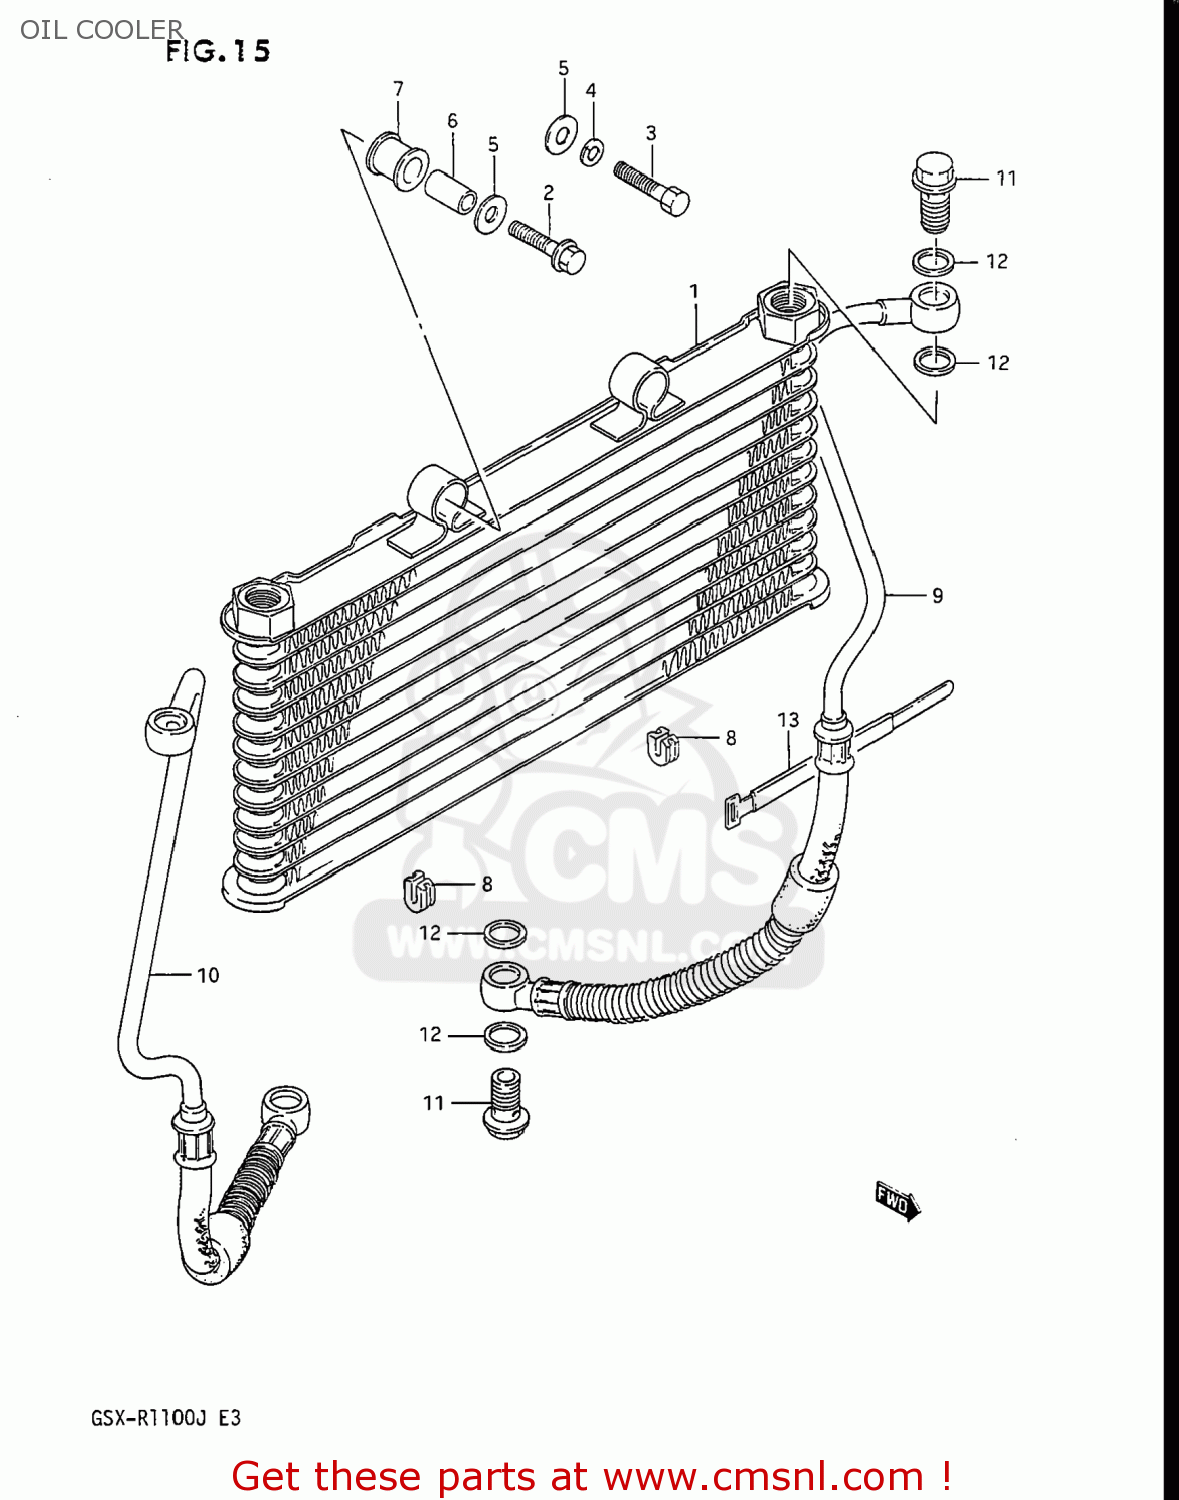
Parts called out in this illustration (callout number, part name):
1	COOLER ASSEMBLY,OIL
2	BOLT 8X40
3	BOLT 8X40
4	WASHER,LOCK,8.
5	WASHER(8.5X23X1.2)
6	SPACER (8.8X12X24.5)
7	CUSHION,OIL COOLER NO.1
8	CUSHION,OIL COOLER NO.2
9	HOSE,OIL COOLER,L
10	HOSE,OIL COOLER,RIGHT
11	BOLT UNION
12	GASKET(16X22X2) (NAS)
13	CLAMP
